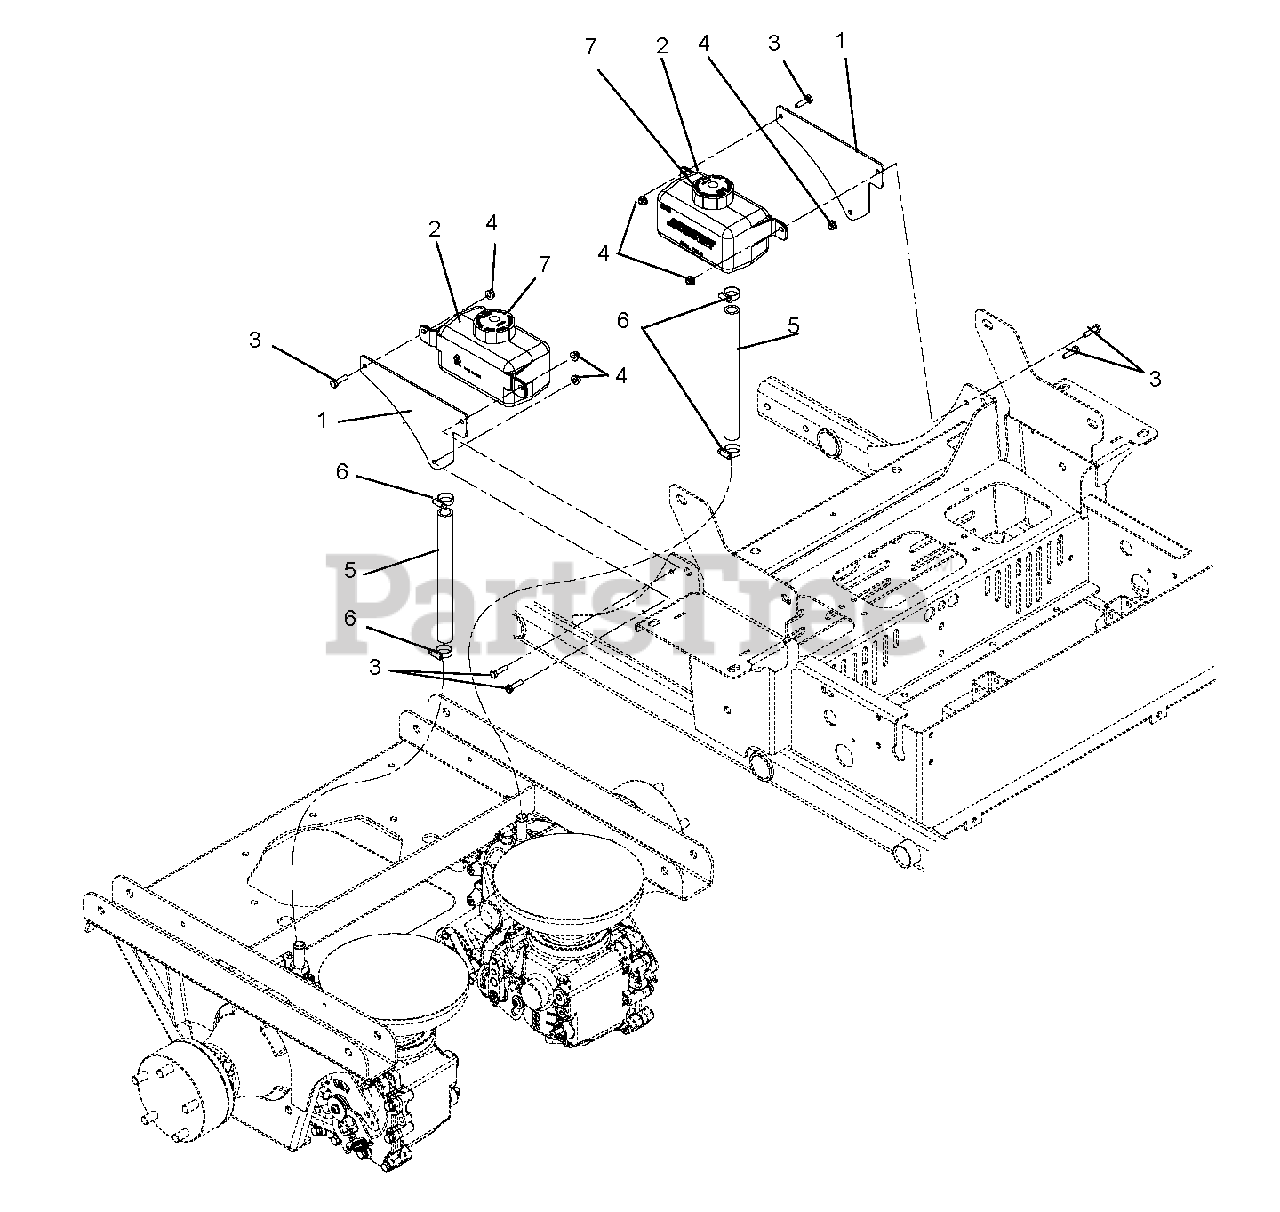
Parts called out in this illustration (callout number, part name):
1	Plate, Hydro Overflow Tank Mounting
2	Tank, Hydraulic 1000ML
3	Bolt, Hex .25-20 x 1.00 GR5 YWZC
4	Nut, Locking Nylon Flange .25-20 YWZC
5	Hose, Hydro Overflow
6	Clamp, .88 DIA. Hose
7	Cap, Hydro Reservoir REPLAC.
